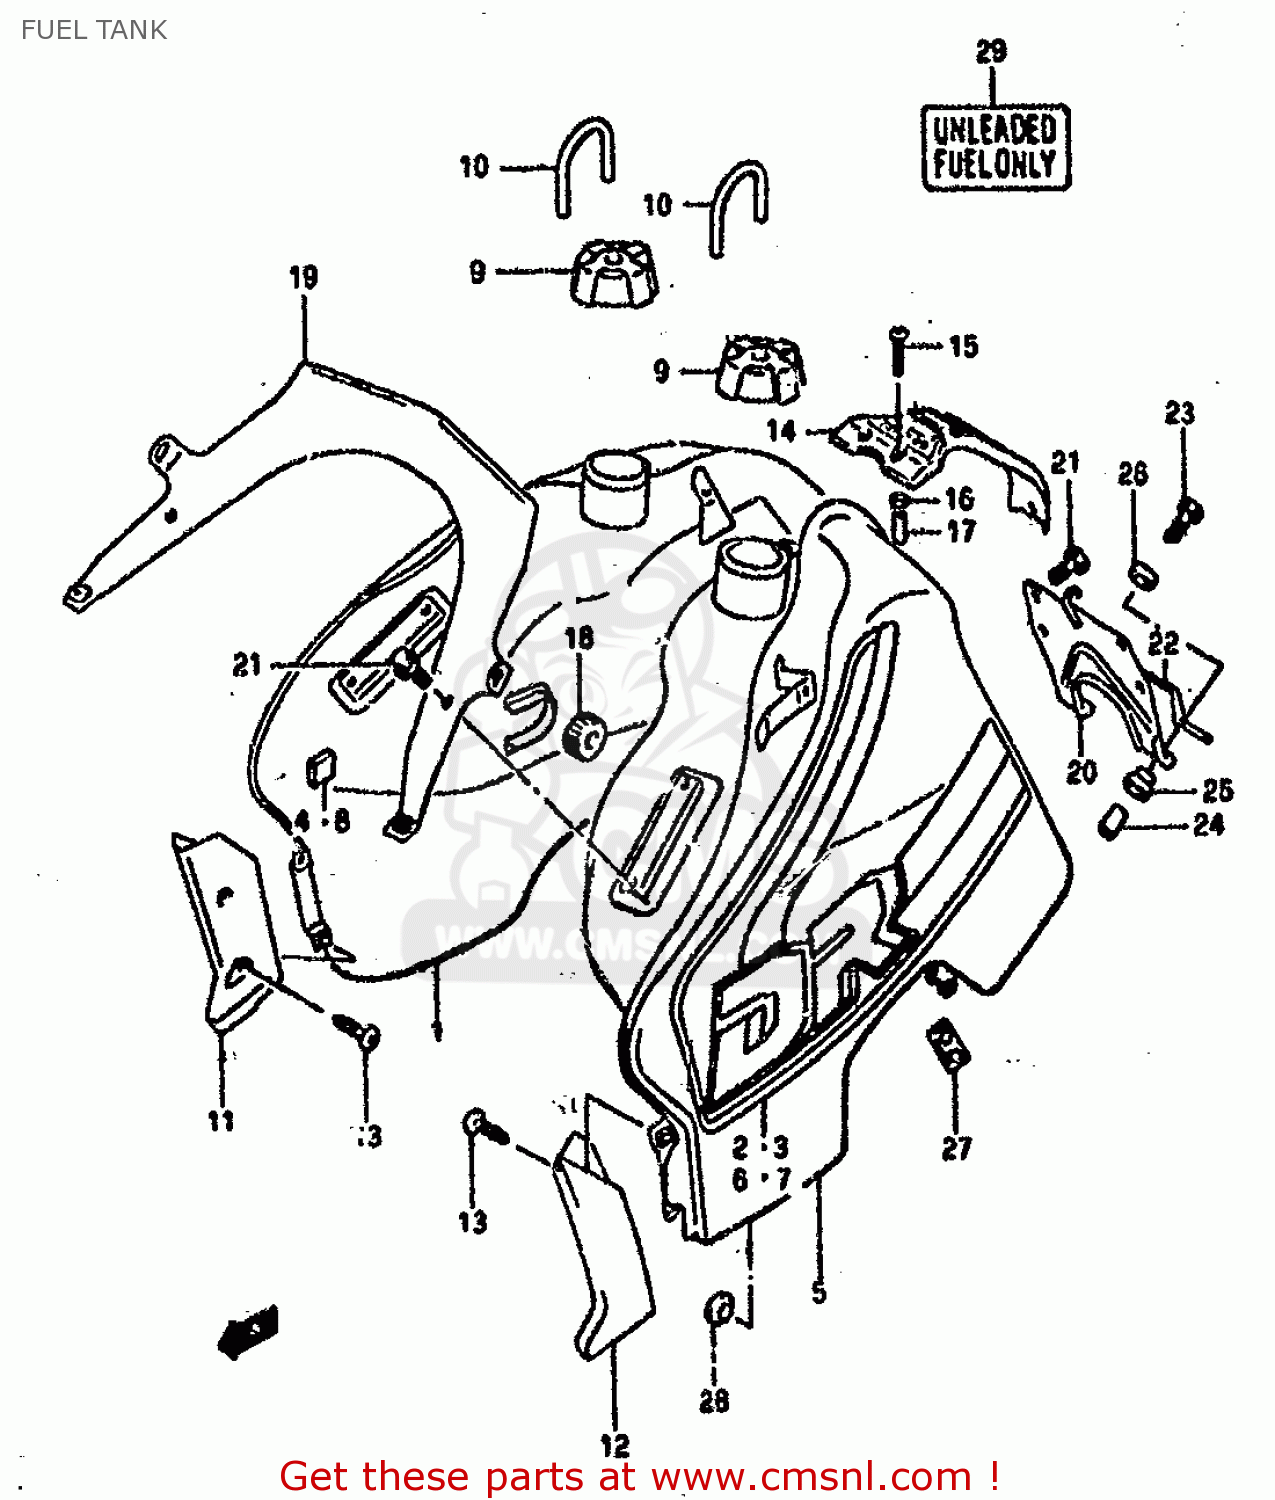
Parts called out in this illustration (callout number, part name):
1	TANK ASSY,FUEL RH (BLUE)
2	TAPE,FUEL TANK RH
3	TAPE,FUEL TANK RH
4	CUSHION
5	TANK ASSY,FUEL LH (RED)
6	TAPE,FUEL TANK
7	TAPE,FUEL TANK
8	CUSHION
9	CAP ASSY,FUEL TANK
10	HOSE
11	COVER,FUEL TANK FR,R
12	COVER,FUEL TANK FR,L
13	SCREW
14	COVER,FUEL TANK CTR
15	SCREW (6X40)
16	WASHER
17	SPACER
18	CUSHION
19	BRACKET,FRONT
20	BRACKET,REAR
21	BOLT
22	BRACKET,SEAT FRONT HOOK
23	BOLT
24	SPACER
25	CUSHION
26	CUSHION
27	CUSHION
28	CUSHION
29	LABEL,FUEL CAUTION
